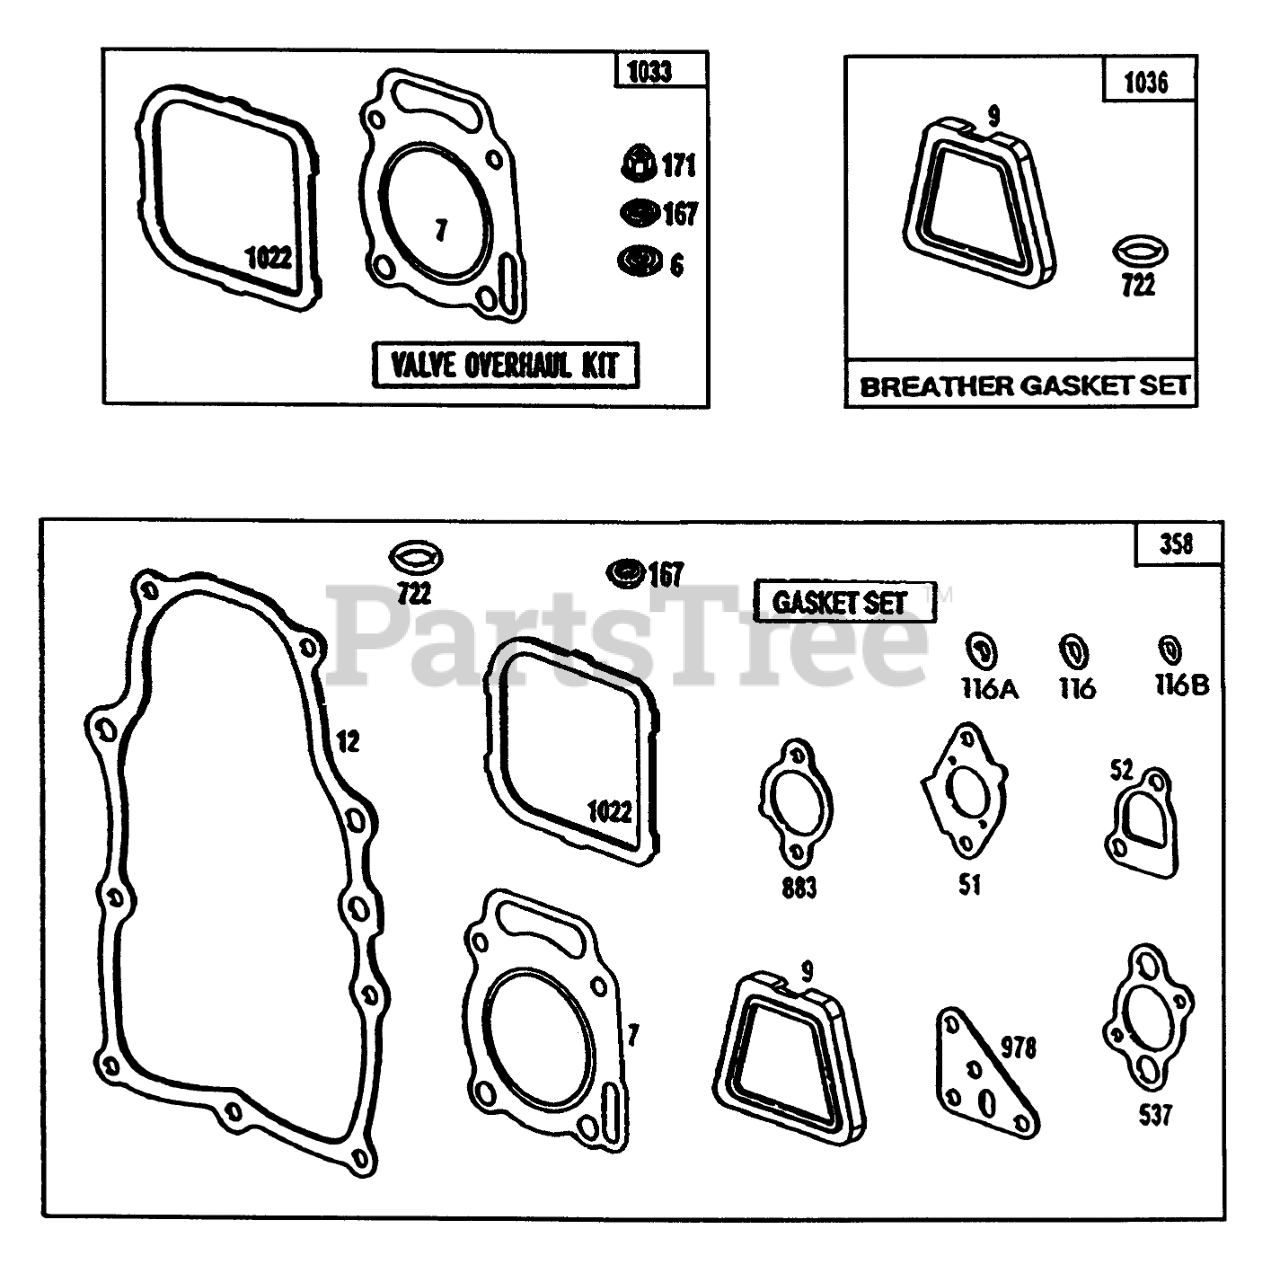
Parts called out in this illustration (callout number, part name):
6	Washer
7	Gasket-Cylinder Head
9	Nut
12	Screen
51	Gasket
52	Gasket-Intake Manifold
116	"O"Ring
116A	"O"Ring
116B	Kit-Gasket Sealing
167	Washer
171	Nut
265	CLAMP - CASING
358	Set-Gasket
522A	Bushing-Shaft
537	Gasket-Air Cleaner
634A	Collar-Throttle
722	Seal-Breather Screw
729	GROMMET
883	GSKT-EXHST MANIFOLD
978	Gasket
1022	Gasket
1033	Kit-Valve Overhaul
1036	Set-Breather Gasket
